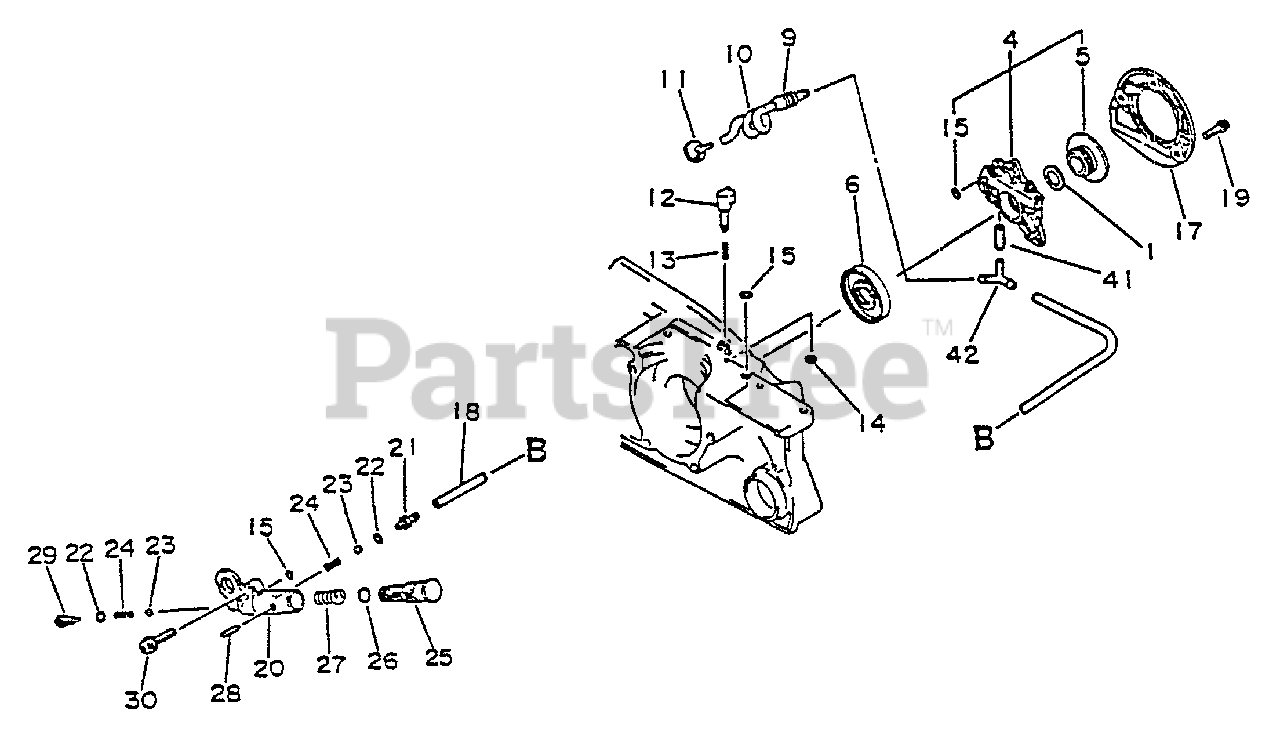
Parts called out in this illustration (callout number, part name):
4	AUTO-OILER ASSY
5	WHEEL, WORM
6	SEAL, OIL
10	PIPE - OIL
11	FILTER, OIL
12	DIAL, AUTO-OILER
14	RING, RETAINING - 3
15	O-RING - 3
17	COVER, OIL PUMP
18	PIPE - 3X6X210 -- BLACK
19	SCREW - 4X14
20	BODY, OIL PUMP
23	VALVE, BALL
24	SPRING, VALVE
25	PISTON, OIL PUMP
26	O-RING - 7
28	PIN - SPRING -- 2X16
29	ADAPTER, OIL PUMP
30	SCREW - 5X14
41	PIPE - 3X6X20 -- BLACK
42	CONNECTOR, PIPE
